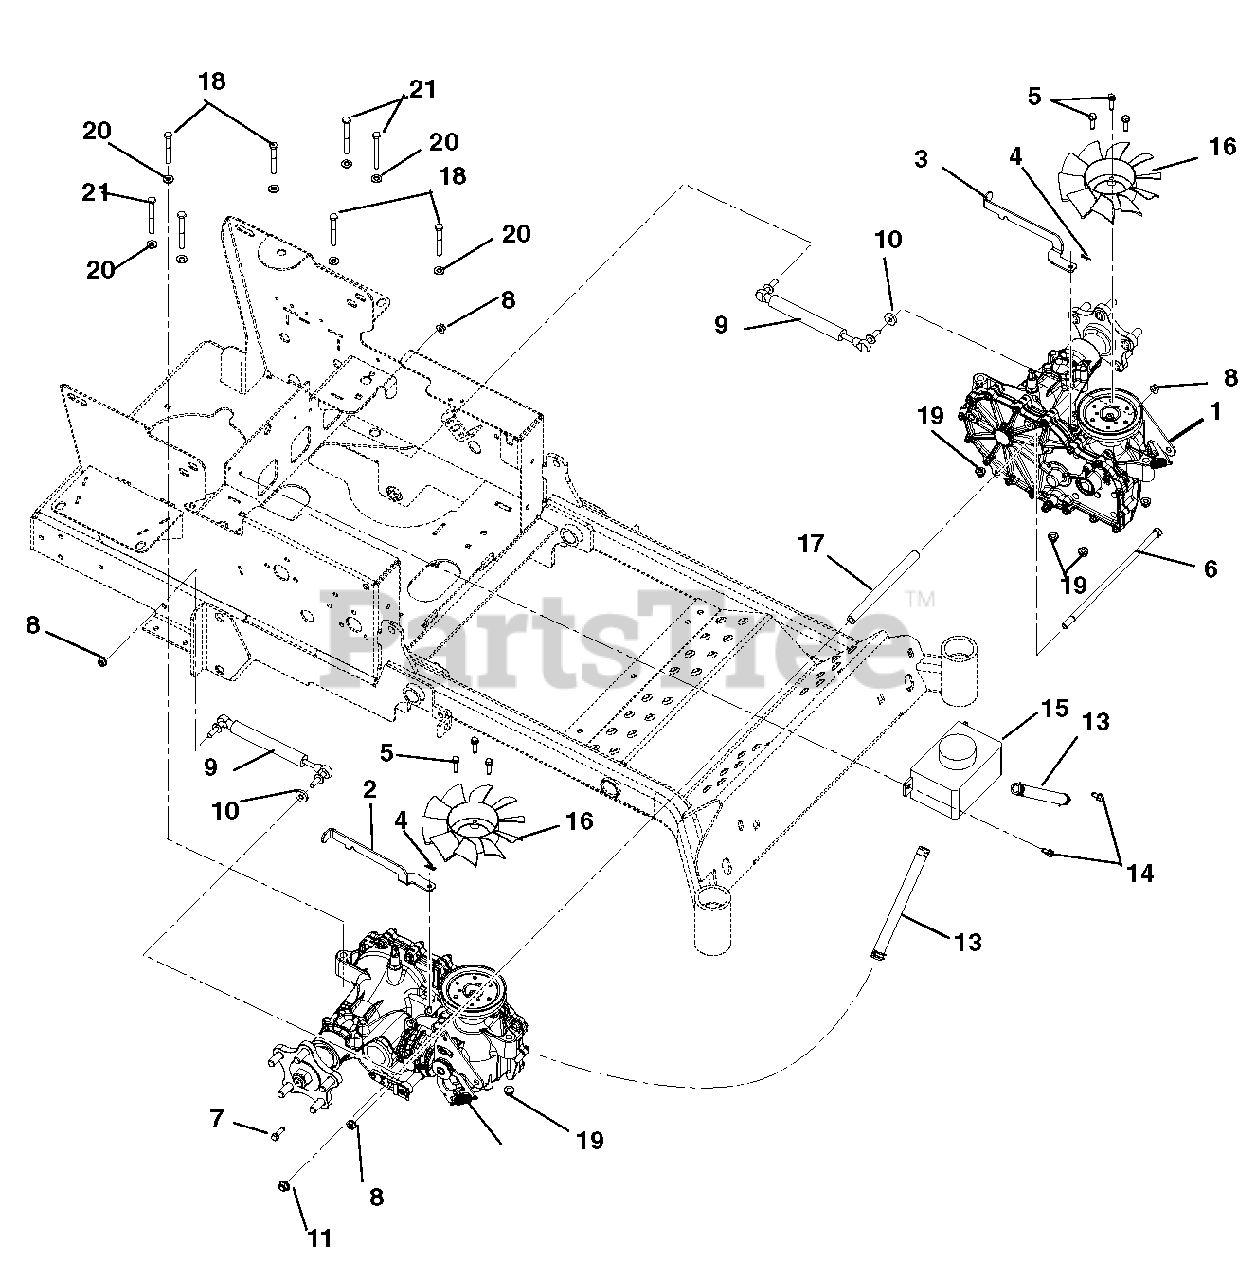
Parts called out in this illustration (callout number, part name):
1	Transaxle, 3100 Series- Left Hand (page 14)
2	Right Hand Dump Valve Lever- Black
3	Left Hand Dump Valve Lever-Black
4	Pin-Hair-Internal .06 x .18 x .77
5	Screw, Tapping .25-20 x 1.00 Hex Washer Head Thread
6	Bolt, Hex .38-16 x 11.00 Grade 5
7	Screw, Machine 8-32 x 1.00 Hex Washer Head
8	Nut, Flange Patch M8-1.25
10	Washer, Flat-Steel .38 x .87 x .179
11	Nut, .38-16 Nyloc Flange
12	Nut, Locking-Nylon 8-32
13	Assembly, Hydro Overflow Tank Hose
14	Screw, Tapping .25-20 x .50 Hex Washer Head Thread
15	Tank, Expansion
16	Fan, Cooling
17	Spacer, .38 ID x 5/8 OD x 7.72
18	Bolt, Hex .31-18 x 2.50 Grade 5
19	Nut, Nyloc Flange .312-18
20	Washer, Flat-Steel .344 x .688 x .065
21	Bolt, Hex .31-18 x 3.00 Grade 5
